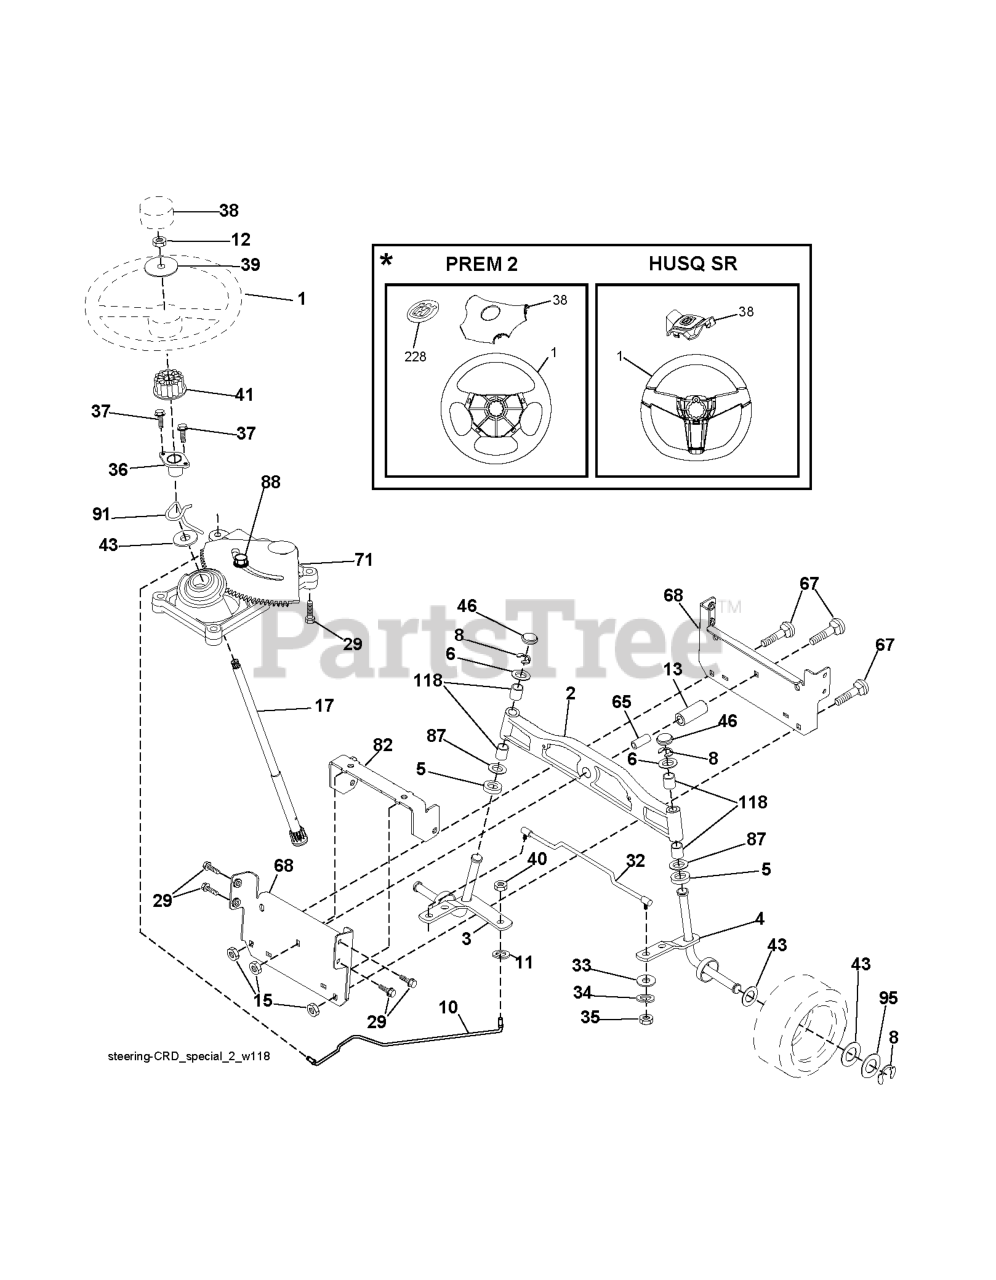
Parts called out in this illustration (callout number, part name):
2	AXLE ASSY FRONT
3	SPINDLE.ASM.LH.15"TIRES
4	SPINDLE.ASM.RH.15"TIRES
5	THRUST WASHER
10	DRAGLINK.15".TIRES.2001
11	WASHER, LOCK 3/8
12	NUT.HEX.1/2-20
13	TUBE, PIVOT AXLE
15	NUT
17	SHAFT ASM STRG
29	SCREW, 3/8-16X3/4
33	WASHER M
34	WASHER.LOCK.HVY.HLCL.SPR.5/16
35	NUT, CROWNLOCK
36	BUSHING, STRG. BLK
37	SCREW.TT.#10-32X.5.3/8.FLANGE
38	RP INSERT.CAP.WHL.STRG.HUSQ.
39	WASHER 9/16"ID, 2 3/8"OD
40	NUT CROWNLOCK 3/8-24
41	ADAPTER, WHEEL STNG..
46	CAP.SPINDLE.BLACK
65	SPACER BRACE AXLE
67	BOLT CARRIAGE
68	BRACE.AXLE.15"TIRES
71	STEERING ASM
82	BRACKET.SUSP.CHASSIS.FRONT.15
87	WASHER, FLAT .781 X 1 1/2"
88	BOLT, SHOULDER 7/16-20
91	CLIP.STEERING
95	WASHER.HARDENED
118	BUSHING, AXLE CAST
228	DECAL.WHEEL.STRG.LGN.H
